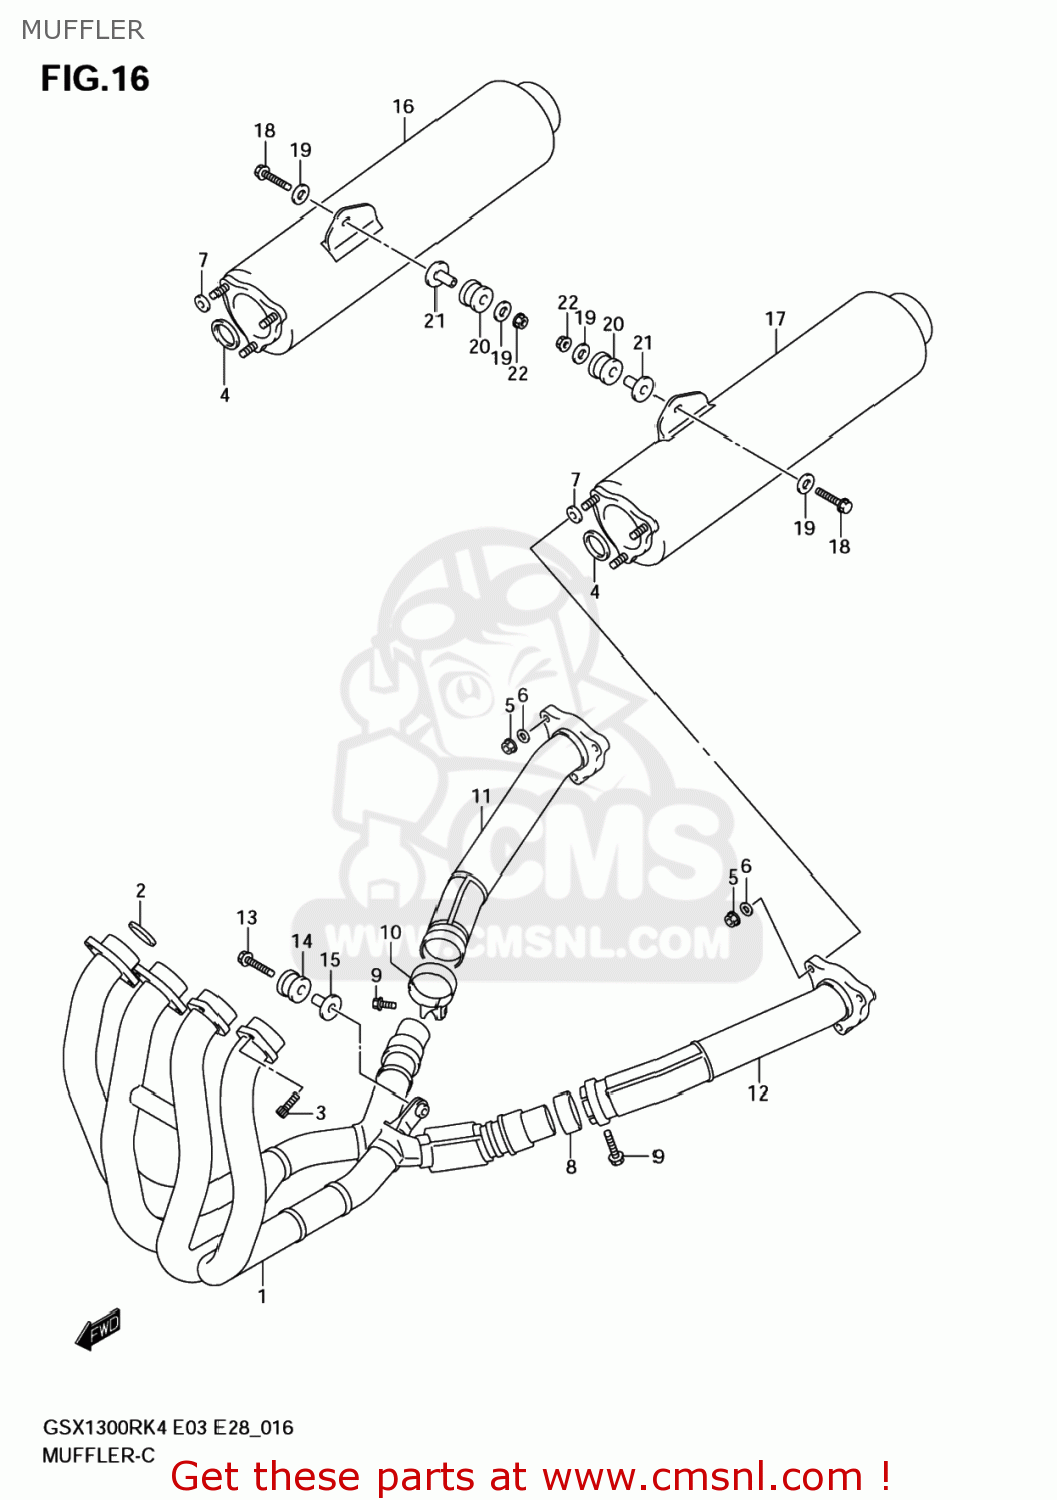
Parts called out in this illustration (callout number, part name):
1	EXHAUST
2	GASKET,EXHAUST PIPE (NAS)
3	BOLT
4	GASKET,MUFFLER JOINT
5	NUT
6	WASHER(8.5X18X1.6)
7	O RING(D:1.9,ID:7.8)
8	CONNECTOR,MUFFLER
9	BOLT
10	CLAMP,CONNECTOR MUFFLER,R
11	PIPE,JOINT,R
12	PIPE,JOINT,L
13	BOLT 8X45
14	CUSHION
15	SPACER(8.6X12X24.2)
16	BODY,MUFFLER,R
17	BODY,MUFFLER,L
18	BOLT(8X45)
19	WASHER(8.5X28X1.5)
20	CUSHION
21	SPACER(8.6X12X27.1)
22	NUT
